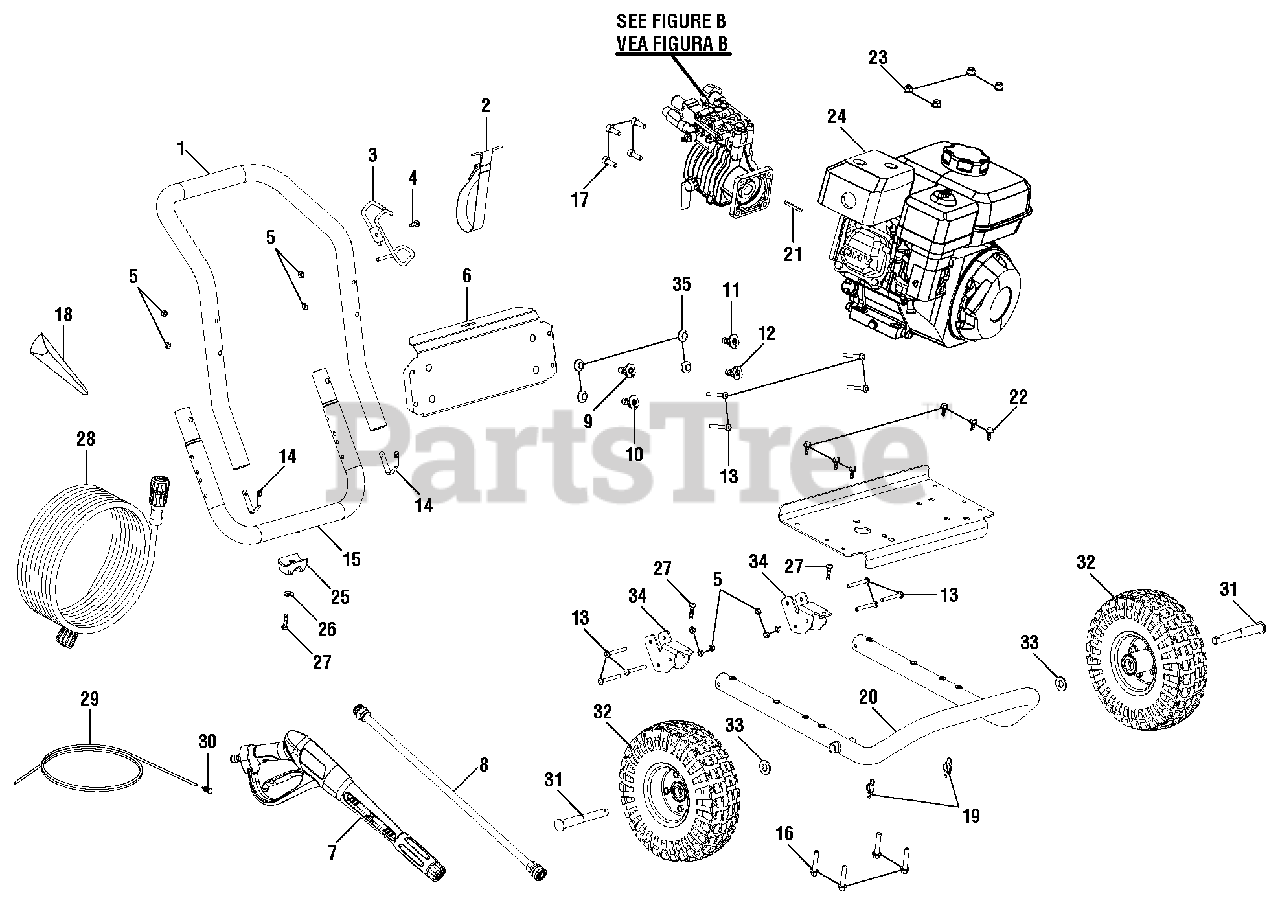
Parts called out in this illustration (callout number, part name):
1	Handle w/Foam
2	Velcro Strap
3	Wand Holder
4	Screw (M6 x16 mm, Phillips Pan Hd.)
5	Lock Nut (M6)
6	Hose and Nozzle Holder
7	Trigger Handle Assembly
8	Extension Wand
9	0deg Nozzle
10	25deg Nozzle
11	40deg Nozzle
12	Soap Nozzle
13	Screw, (M6 x 48 mm, T30 Torx Hd.)
14	Lock Button w/Spring Clip
15	Rear Frame Assembly
16	Bolt (M8 x 40 mm, Hex Hd.)
17	Bolt (5/16-24 x 3/4 in., Hex Hd.)
19	Retaining Ring
20	Main Frame Assembly
21	Output Shaft Key
22	Bolt (M6 x 16 mm, Flange Hd.)
23	Lock Nut (M8 x 1.25 mm, Flange)
25	Rubber Foot
26	Washer (1/4 in.)
27	Bolt (M6 x 25 mm, T30 Torx Hd.)
28	Hose (25 ft.)
29	Detergent Injection Tube
30	Detergent Injection Filter
33	Washer (1/2 in.)
34	Frame Connector
35	Rubber Grommet
